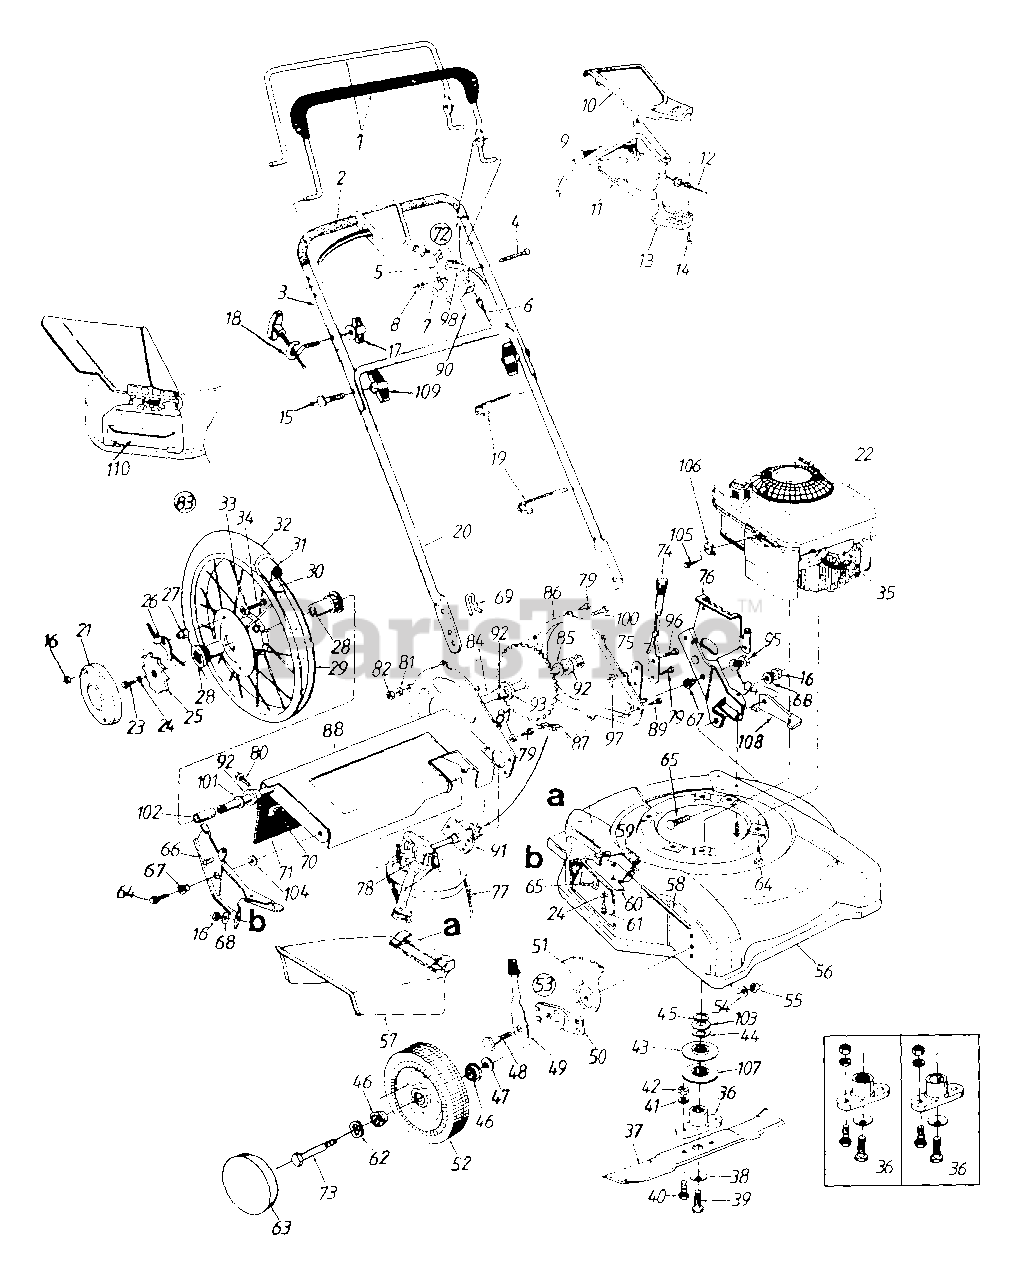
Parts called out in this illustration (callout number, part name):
1	Control Handle Ass'y.
2	Foam Grip
4	Oval C-Sunk Scr.
5	Throttle Body
6	Control Cable - 39" Lg.
7	Spring Wash. .66" I.D.
8	Hex L-Nut 1/4 - 20 Thd.
9	Control Lever
10	Control Cover Half - Upper
11	Control Cover Half - Lower
12	Self-Propelled Cable - 48" Lg.
13	Cable Mounting Cap
14	Fl - "C" Sunk Hd. Tap Scr. #10 x .75" Lg.
15	Curved Hd. Bolt 5/16 - 18 x 2" Lg.
16	Hex Nut 5/16 - 18 Thd.
17	Handle Knob 1/4 - 20 Thd.
18	Rope Guide
19	Cable Tie
21	Wheel Cover
22	Engine
23	Hex Bolt 1/4 - 20 x .75" Lg. (Gr. 5)
24	Bell-Wash. 1/4" I.D.
25	Wheel Ratchet
26	Pawl and Spring Ass'y.
27	Special Hex Nut 5/16 - 18 Thd.
28	Flange Bearing .63" I.D.
29	Rim Ass'y. Only 16" x 2.1"
30	Rimstrip 16" x 7/8"
31	Inner Tube 16" x 2.12"
32	Chevron Tire 16" x 2.125"
33	Intern. L-Wash. 5/16" I.D.
34	Hex Bolt 5/16-18 x 1.0" (Gr. 5)
35	Spark Plug Boot
36	Blade Adapter Kit
37	22" Blade
38	Bell-Wash. .39" I.D.
39	Hex Bolt 3/8 - 24 x 1.5" Lg.
40	Hex Bolt 3/8 - 24 x 1" Lg.
41	L-Wash. 3/8" I.D.
42	Hex Nut 3/8 - 24 Thd.
43	Upper Pulley Half
44	Fl-Wash. .88" I.D.
45	Crankshaft Spacer
46	Ball Bearing 1/2" I.D.
47	Bell-Wash. .38" I.D.
48	Shld. Bolt .5"
49	Spring Lever Ass'y. w/Knob
51	Height Adj. Plate
52	Wheel Ass'y. Comp.
53	Height Adj. Ass'y. Comp. - R.H.
54	Bell-Wash. .39" I.D. x 1.38"
55	Hex Nut 3/8 - 16 Thd.
58	Hinge Pin
59	Torsion Spring
60	Adapter Plate
61	Hex TT-Tap Scr. 1/4 - 20 x .5"
62	Wave Wash. .51" I.D. x .78"
63	Hub Cap
64	Hex TT-Tap Scr. 3/8 - 16 x 1"
65	Carriage Bolt 5/16 - 18 x .62" Lg.
68	Bell-Wash. 5/16" I.D.
69	Intern. Cotter Pin 5/16" Dia.
70	Retaining Strip
71	Rear Flap
72	Throttle Box Comp.
73	Front Axle Bolt
75	Height Adjustment Lever
78	Transmission Comp.
79	Hex Tap Scr. 1/4 x .38" Lg.
80	Hex Tap Scr. 1/4 x .62" Lg.
81	L-Wash. 1/4" I.D.
82	Hex Nut 1/4 - 20 Thd.
83	Wheel Ass'y. Comp.
84	Sprocket and Axle Ass'y.
85	Fl-Wash. .635" I.D. x 1.0" O.D.
90	Throttle Cable
92	Hex Flange Brg. .631" I.D.
93	Spacer .63" I.D. x 1.25"
95	Hex L-Nut 3/8 - 24 Thd.
96	Hex Bolt 3/8 - 16 x .62" Lg.
97	Flanged L-Nut 3/8 - 16 Thd.
98	Throttle Lever
100	Hex Bolt 1/4 - 20 x .5" Lg.
101	Fl-Wash. .632" I.D. x .943"
102	Spacer .628" I.D. x .875"
103	Spr. Wash. .89" I.D.
104	Fl-Wash. .38" I.D. x 1" O.D.
105	Wash. Hd. Scr. #10 - 32 x .62" Lg.
106	Casing Clamp
107	Lower Pulley Half
108	Deck Bracket
109	Hand Knob
110	Mulching Baffle
